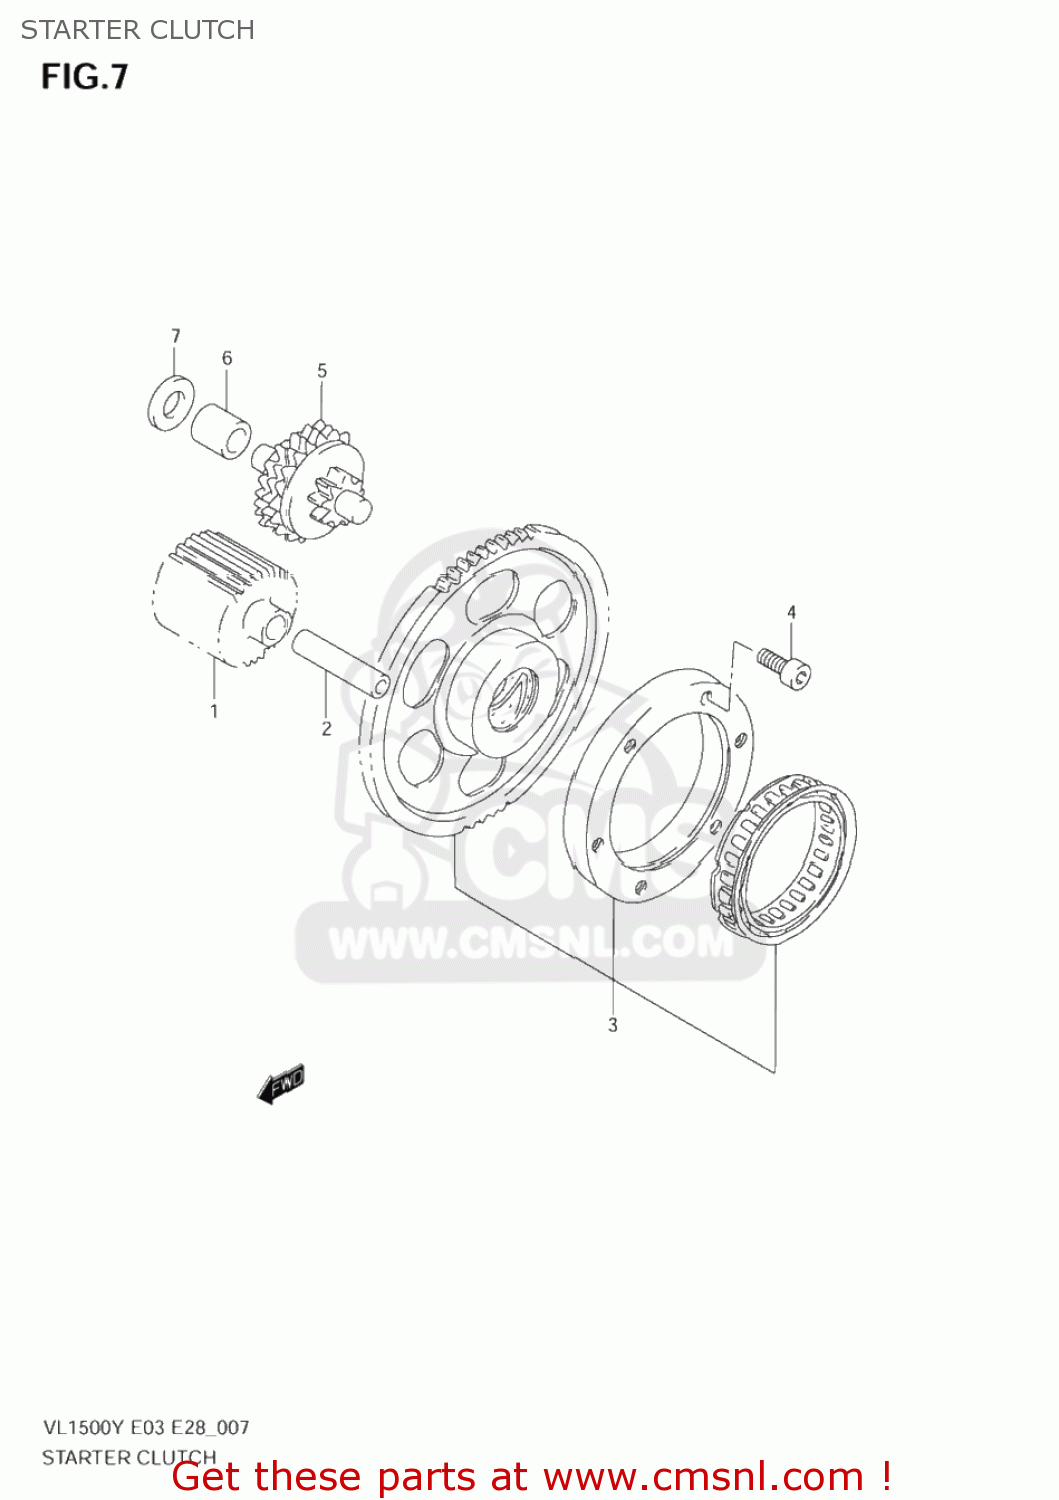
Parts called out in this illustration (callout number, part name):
1	GEAR,STARTER IDLE NO.1
2	PIN(7X11X55)
3	CLUTCH SET,STARTER
4	BOLT
5	LIMITER ASSEMBLY,STARTER IDLER GEAR
6	BUSH,LIMITER GEAR SHAFT
7	SHIM(10X20X1)
